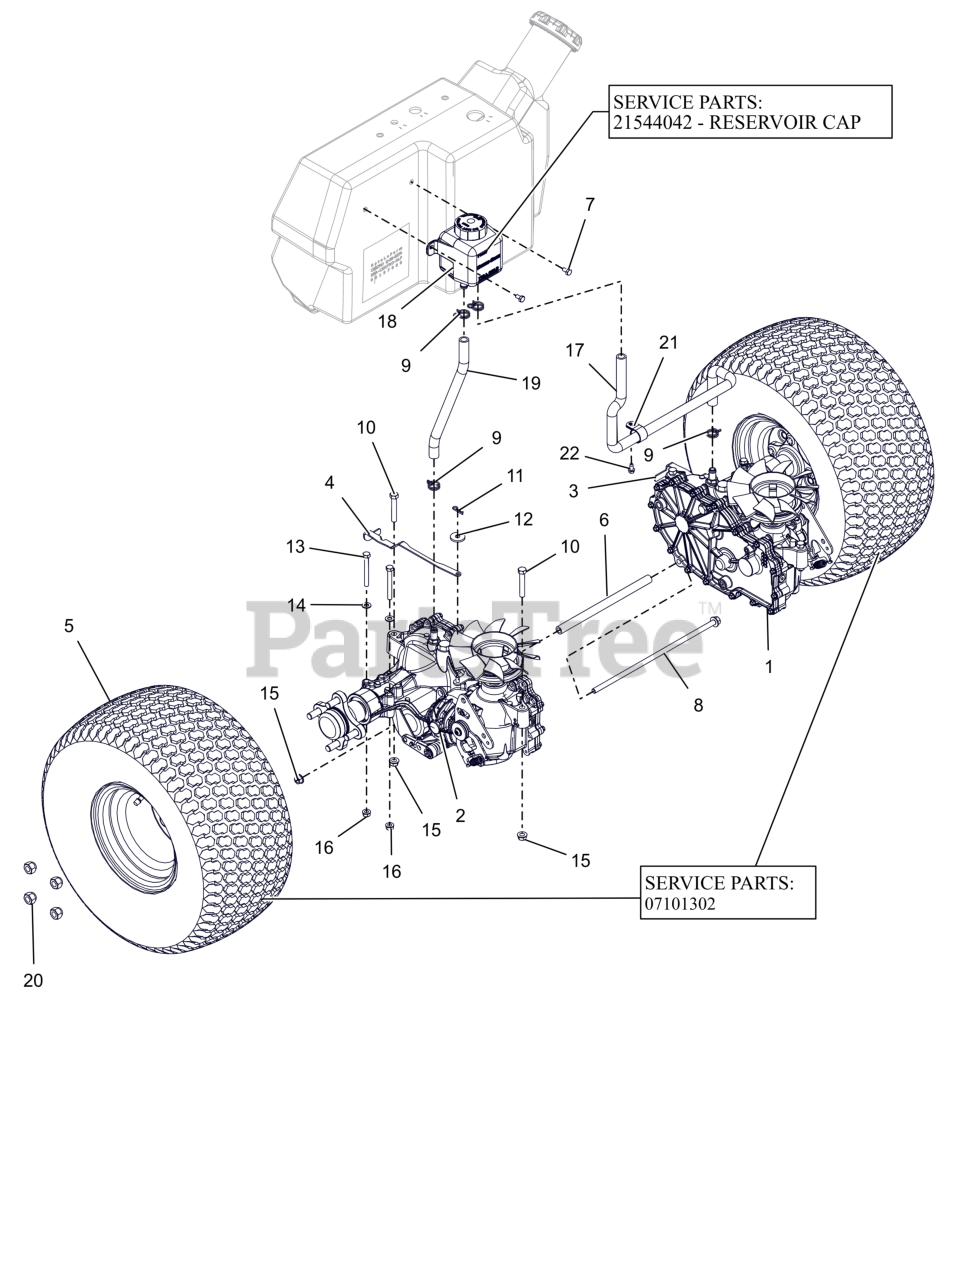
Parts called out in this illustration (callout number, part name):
1	TRANSAXLE, LH - ZT-3400
2	TRANSAXLE, RH - ZT3400
3	BRKT, HYDRO DUMP - LEFT
4	BRKT, HYDRO DUMP - RIGHT
5	ASSM TIRE/WHEEL 20 X 10.50 - 8
5	TIRE, 20 X 10.5-8 4 PLY RADIAL
6	SPCR, TRANSAXLE .406 ID X .630 OD X 10.464 (BLACK)
7	BLT,HEX .25-20X.50 G5 ZCC
8	BLT, HEX-FLG 0.375-16X13 GR5 ZC120
9	3/4 WIRE HOSE CLMP ZC
10	BLT,HEX .38-16X2.25 G5 ZCC
11	PIN, HAIR #213 .08X1.19 ZCC
12	WSHR, FLT .340X1.125X.135 ZCC
13	BLT, HEX .31-18X2.75 G5 ZCC
14	WSHR,FLT .344X.688X.065 ZCC
15	NUT-LK-CTR-FLG .375-16 GF ZCC
16	NUT,LK-CTR-FLG .31-18 GF ZCC
17	HOSE, PROSTANCE-OVERFLOW LEFT
18	TANK, HYDRO OVERFLOW 700 ML
18	CAP, HYDRO RESERVOIR REPLAC.
19	HOSE, PROSTANCE-OVERFLOW RIGHT
20	NUT, WHEEL .50-20 ZCC
21	CLAMP, COUSHIONED STEEL REV
22	SCR-TAP .25-20X.50 HWH ZCC
